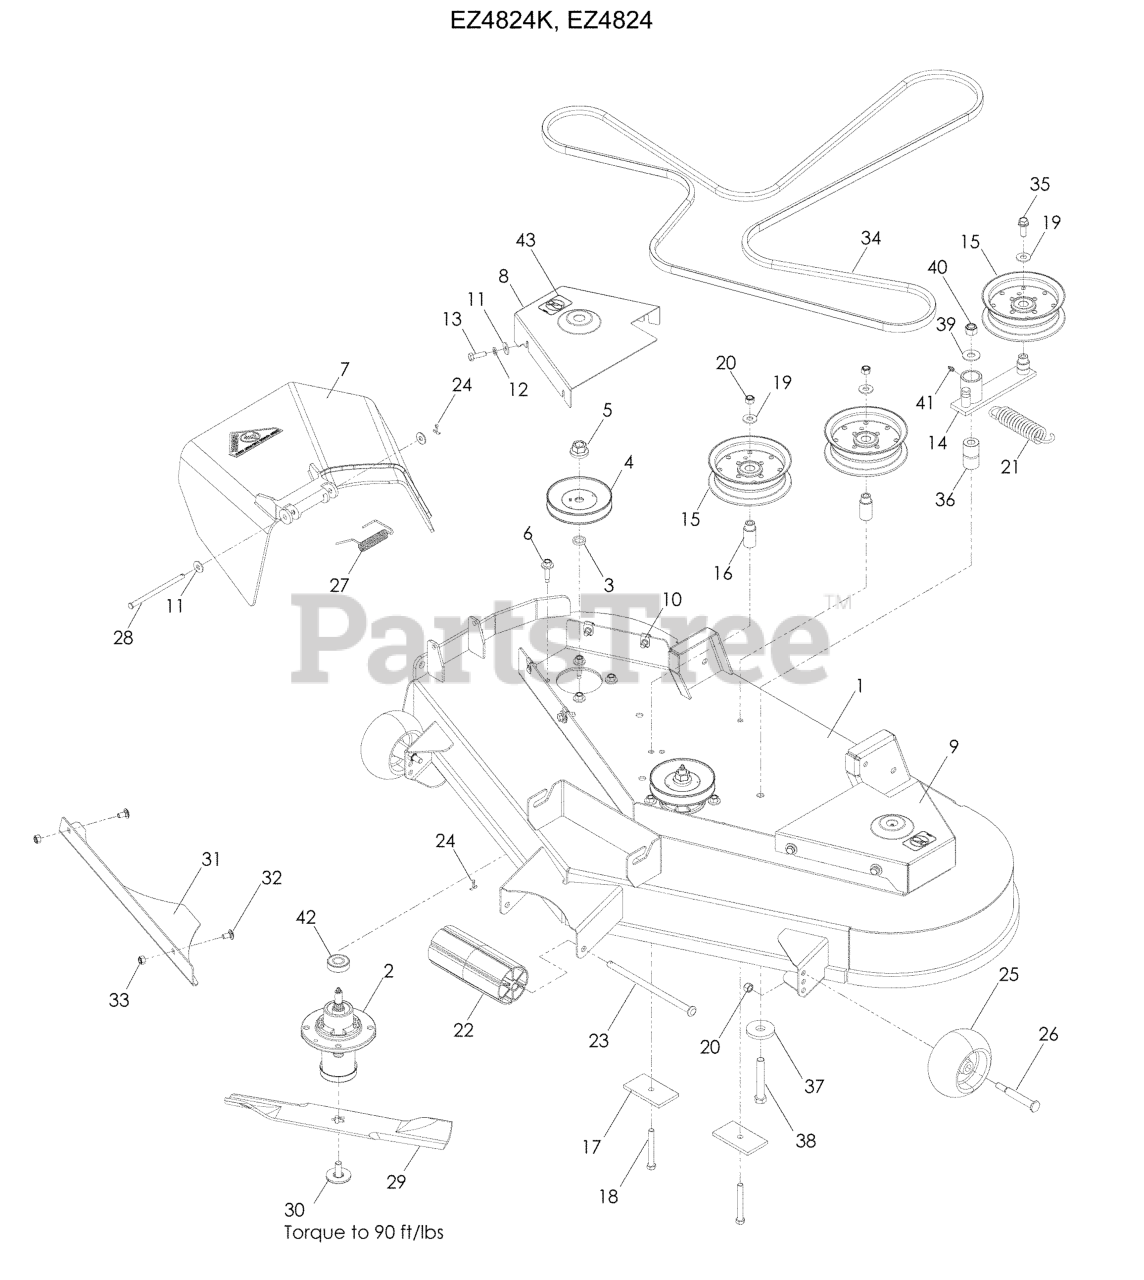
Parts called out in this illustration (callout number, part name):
1	DECK.48".TRI-FORCE.W/DECALS.OR
2	MANDREL.DECK.ASSEMBLY
3	WASHER-SPACER
4	PULLEY MANDREL
5	LOCKNUT - 9/16
6	WASHER HEAD SCREW
7	DISCHARGE CHUTE 48"
8	BELT SHIELD - R.H. ORANGE
9	BELT SHIELD - L.H. ORANGE
10	U-CLIP 5/16-18 NUT RETAINER
11	WASHER 5/16 FLAT
12	WASHER.LOCK.HVY.HLCL.SPR.5/16
13	HCS 5/16C X 3/4
14	PULLEY - IDLER, NYLON
15	PULLEY, IDLER
16	IDLER BUSHING
17	SUPPORT PLATE
18	HCS 3/8C X 3
19	WASHER 3/8 FLAT
20	NUT 3/8-16 NYLOC
22	NOSE ROLLER 48"
23	NOSE ROLLER ROD
24	RP_COTTER PIN 1/8 X 3/4
25	GAUGE WHEEL
26	SHOULDER BOLT 1/2X2-5/8 ZD SPE
27	SPRING - TORSION
28	PIN-CLEVIS 5/16 DIA X 5.19 ZD
29	BLADE, 16-1/4"
30	BLADE BOLT ASSY-7/16" TB REPL
31	CONFINEMENT PLATE 48" BLK
32	CARRIAGE BOLT 5/16C X 5/8"
33	NUT 5/16 NYLOC
34	BELT, DECK
35	4CS 3/8C X 1 SERRATED HEAD
36	PIVOT BUSHING
37	WASHER, SUPPORT
38	HCS 1/2C X 3 1/4
39	WASHER 1/2 FLAT
40	NUT 1/2-13 HEX NYLOC ZD
41	ZERK
42	BEARING, BALL
43	DECAL, NO STEP
